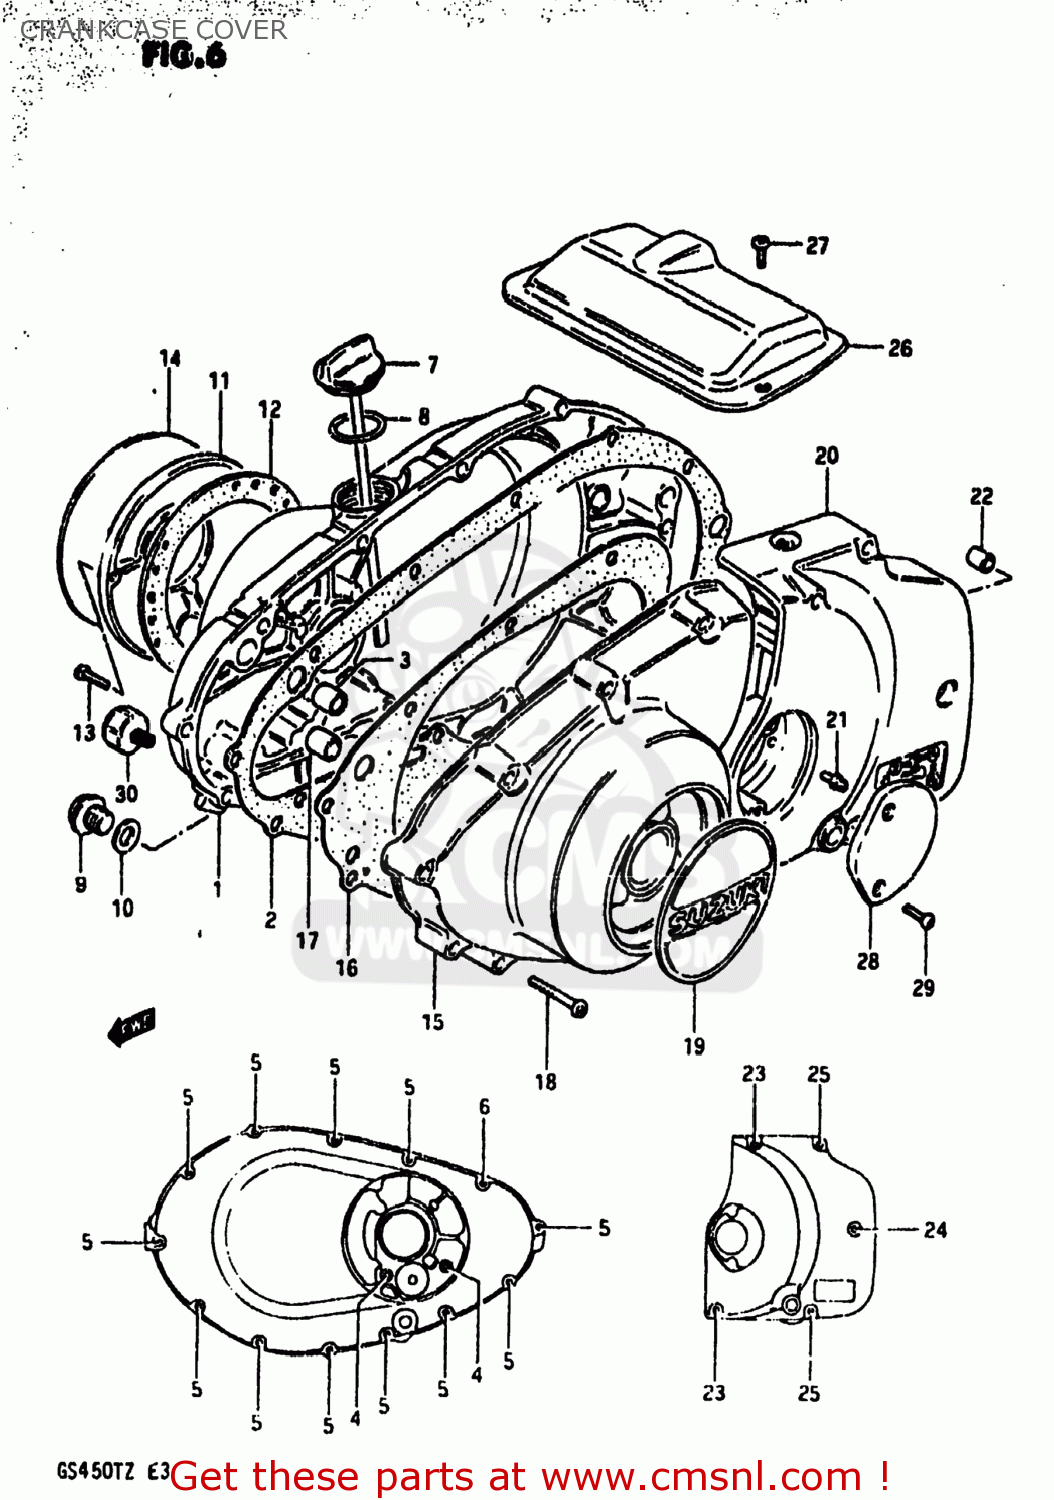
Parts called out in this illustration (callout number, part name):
1	COVER,CLUTCH
2	GASKET,CLUTCH COVER (MCA)
3	PIN
4	SCREW
5	BOLT (6X35)
6	BOLT
7	GAUGE,OIL LEVEL
8	O-RING
9	PLUG (14X12)
10	GASKET(14X19.2X2) (NAS)
11	COVER,CONTACT BREAKER
12	GASKET,CONTACT BREAKER COVER (NAS)
13	SCREW
14	EMBLEM,MAGNETO COVER
15	COVER
16	GASKET,MAGNETO COVER (MCA)
17	PIN
18	BOLT (6X35)
19	EMBLEM,MAGNETO COVER
20	COVER,SPROCKET
21	NIPPLE
22	PIN
23	SCREW 6X65
24	SCREW
25	SCREW
26	COVER,STARTER MOTOR
27	SCREW
28	CAP,CLUTCH RELEASE ADJUST
29	SCREW 5X12
30	SWITCH ASSEMBLY
